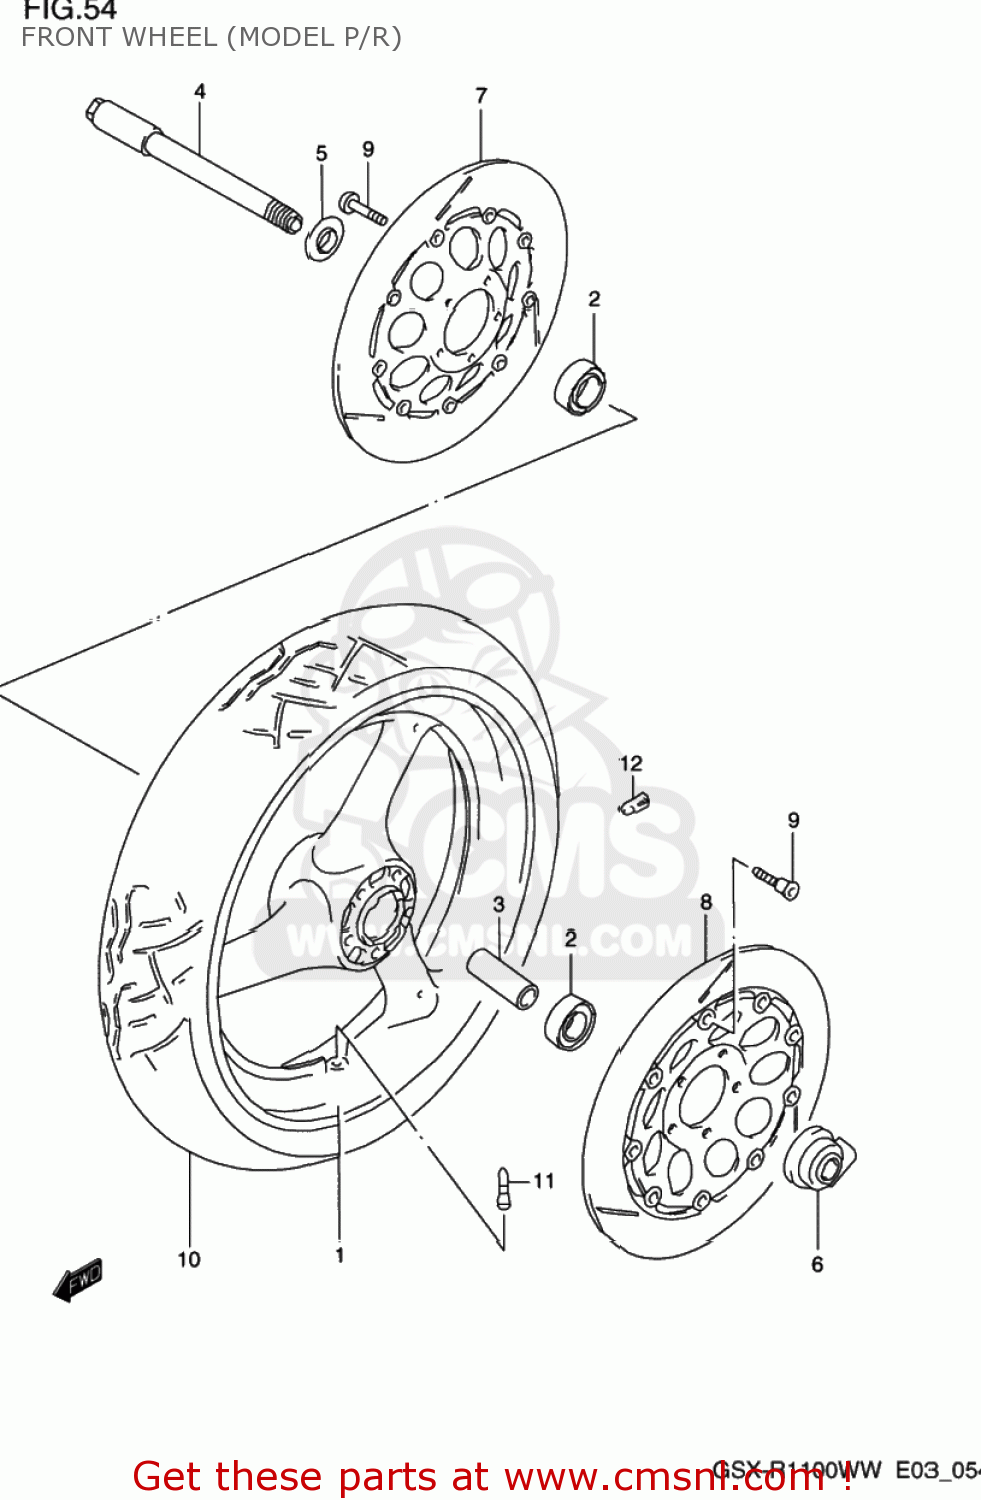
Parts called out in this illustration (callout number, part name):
1	WHEEL,FRONT (17XMT3.50)(
2	BEARING
3	SPACER(20.8X27.2X74)
4	AXLE,FR
5	SPACER,FR HUB BEARING,R
6	BOX ASSY,SPEEDOMETER GEAR
7	DISC,FR BRAKE,R
8	DISC,FR BRAKE,L
9	BOLT 8X33
10	TIRE COMP,FRONT 120/70ZR1
11	VALVE ASSEMBLY,WHEEL,TR412
12	BALANCER,WHEEL
